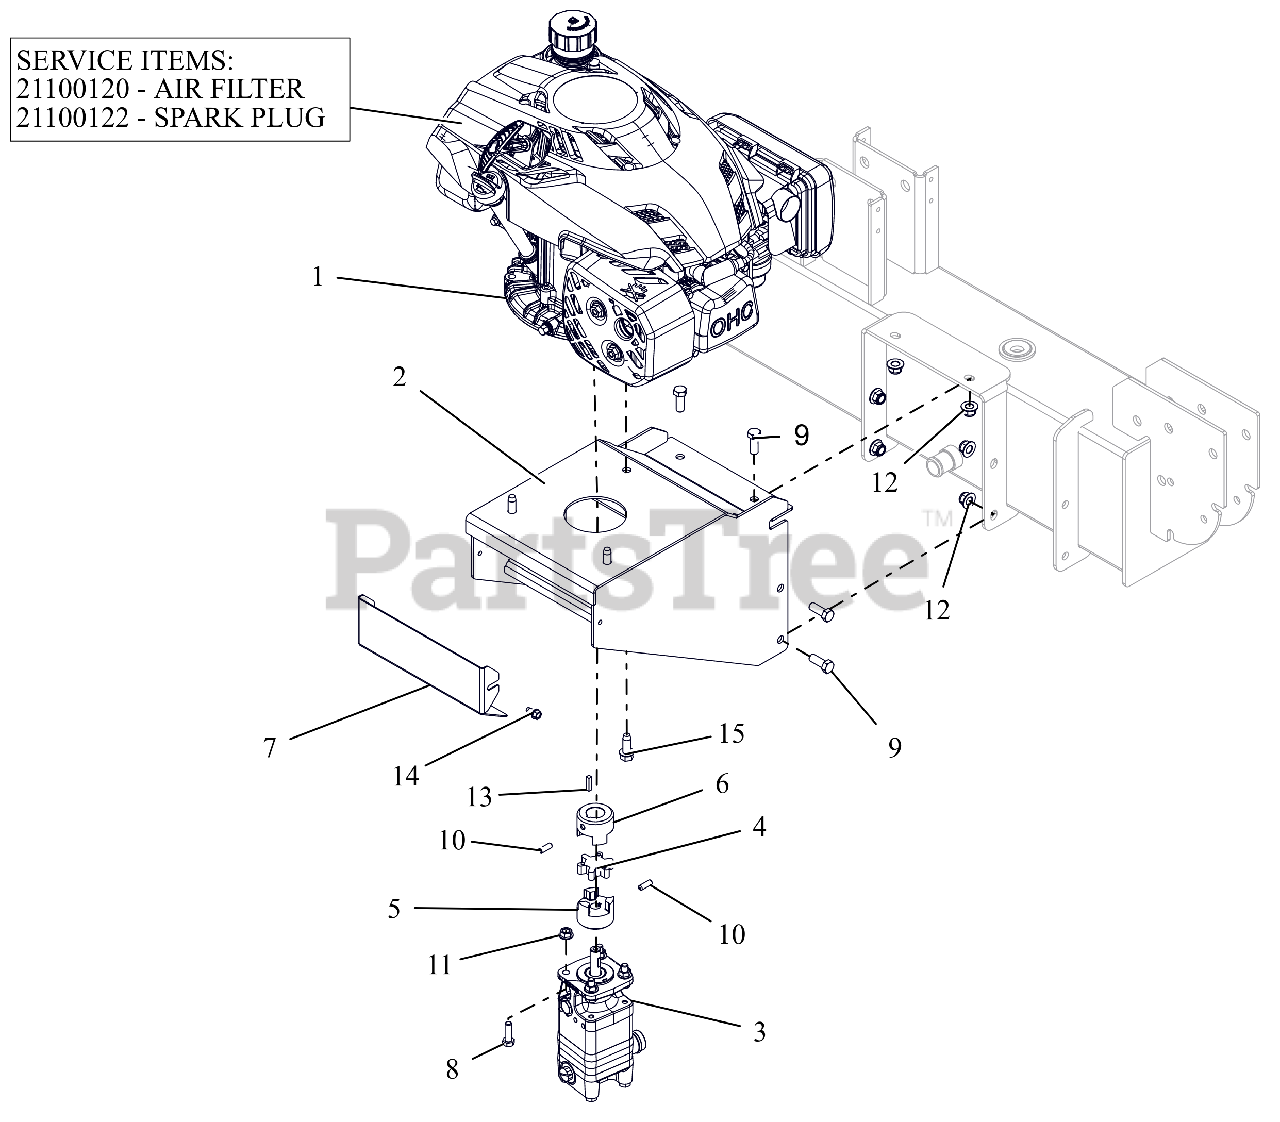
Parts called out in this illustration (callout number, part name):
1	ENGINE, SUBARU EA190 (CARB) LS
1	FILTER, AIR- SUBARU PAPER
1	PLUG, SPARK
2	ENGINE MOUNT W/SAFTY DECAL-27T
3	PUMP,SPLITTER-11 GPM
4	SPIDER - URETHANE
5	COUPLER - DRIVE 1/2"
6	COUPLER - DRIVE, 7/8"
7	COVER-COUPLER
8	@BLT-HEX .31-18X1.00 GR5 YWZC
9	@BLT-HEX .38-16X1.00 GR5 YWZC
10	SCR,SET .25-20X.75 PCPT SH
11	@NUT-LK-TOP-FLG .31-18 YWZC
12	@NUT-LK-NYL-FLG .38-16 YWZC
13	KEY-SQ .188X.75X.188
14	SCR-TAP .25-20X.50 HWH TR YWZ
15	@SCR-TAP .38-16X1.00 HWH TR YZ
